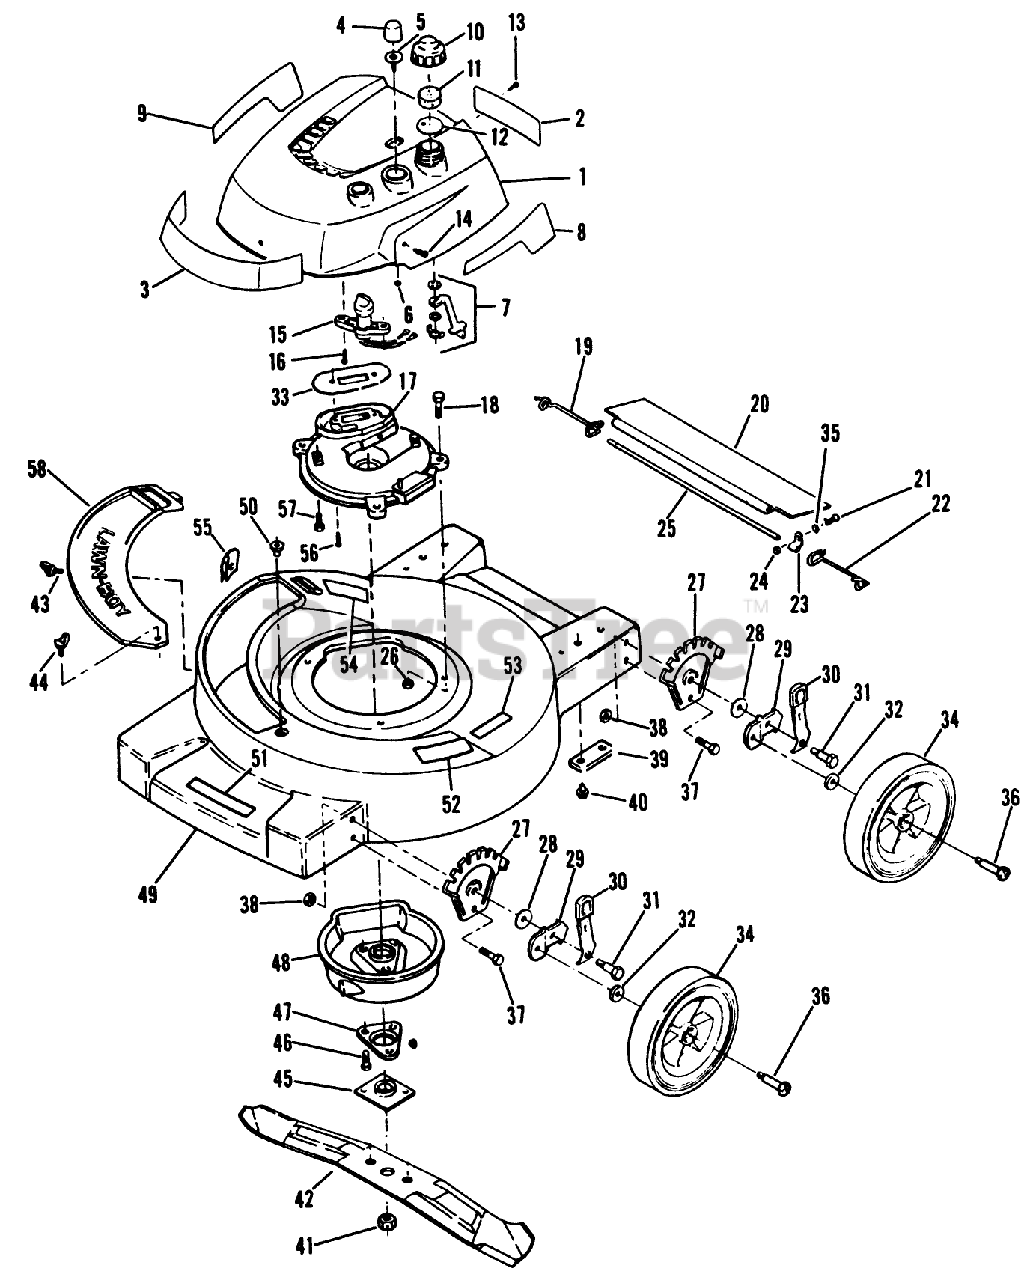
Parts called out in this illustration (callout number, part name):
6	LOCKNUT S
11	BAFFLE - FOAM SM
12	GASKET S
13	SCREW S
14	SCREW S
15	SWITCH
17	PLATE,MUFFLER F
18	SCREW
19	SPRING;TRAILING SHIELD RH
20	SHIELD
22	SPRIG T/SHLD ASOC
23	CLAMP ROD KMC
24	LOCKNUT E
25	ROD 21" ADVANCE
26	NUT-LOCK F
28	WASHER
30	KNOB & SPRING
32	WASHER WROUGHT
35	WASHER F
38	LOCKNUT
40	SCREW
41	NUT-BLADE
44	WING SCREW LAWRE
45	PLATE AND COLLAR ASM
46	SCREW
47	SUPPORT F
52	PAD FOOT
56	SCREW V
58	PLATE
59	WING SCREW LAWRE
61	NUT-LOCK F
